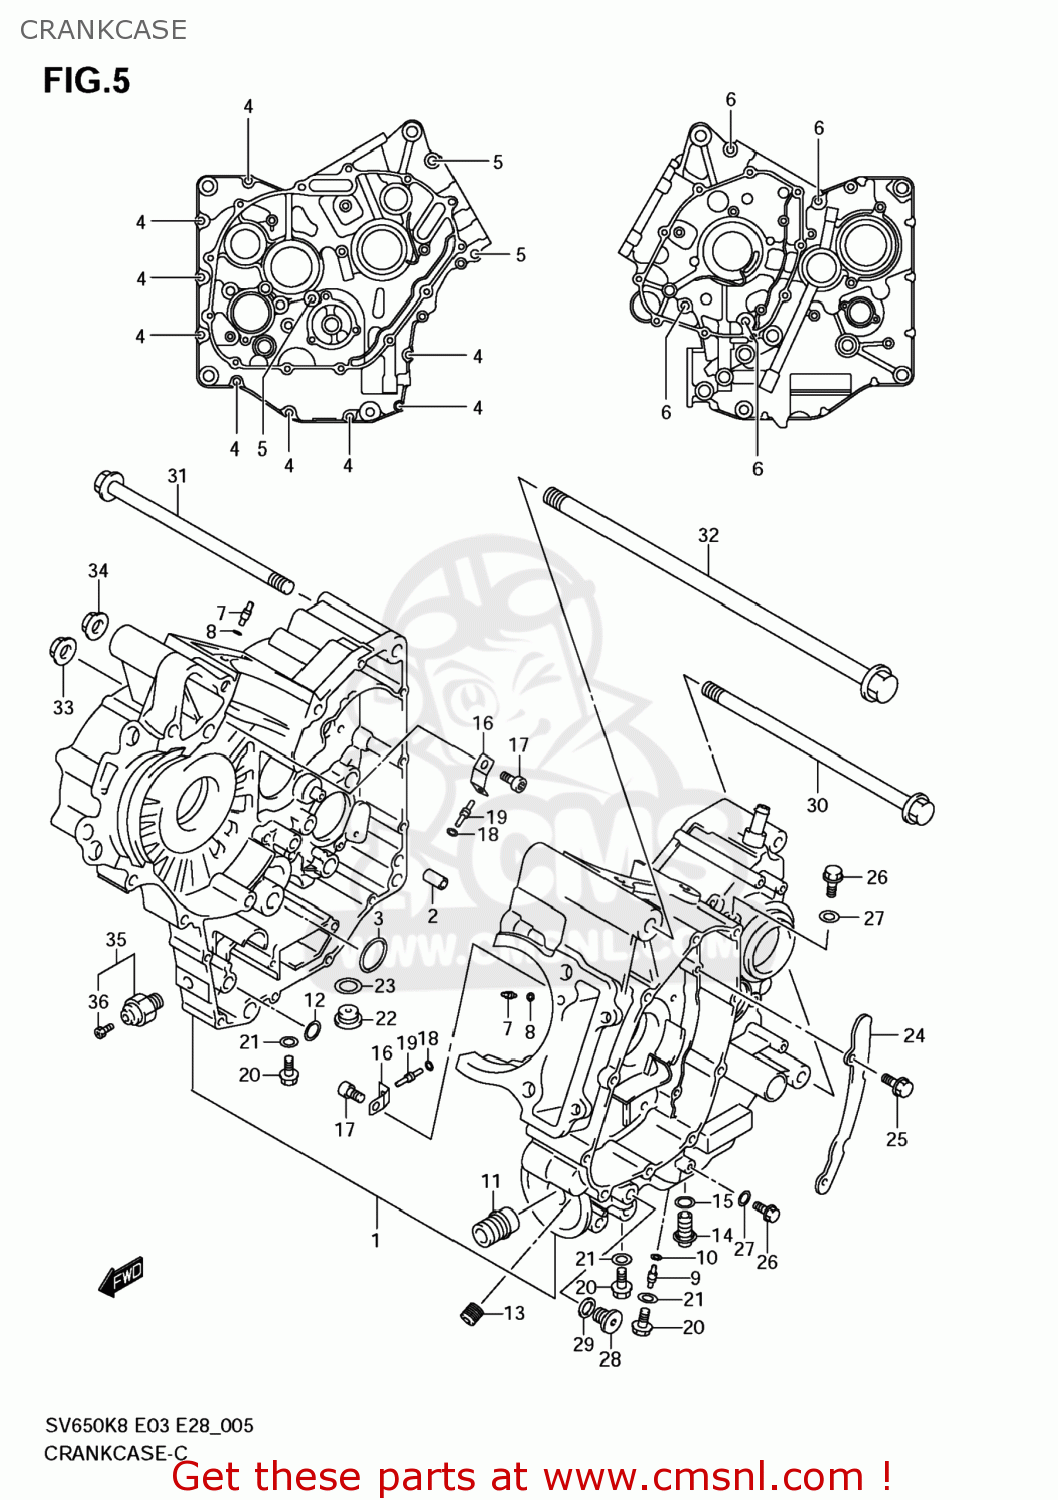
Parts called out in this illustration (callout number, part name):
1	CRANKCASE SET
2	PIN(8.4X11X20)
3	O RING(D:2.4,ID:15.8)
4	BOLT
5	BOLT
6	BOLT
7	JET,AIR(14)
8	O RING(D:1.2,ID:4)
9	JET,AIR(14)
10	O RING(D:1.2,ID:4)
11	UNION,OIL STAND
12	O RING(D:1.9,ID:12.6)
13	JET,OIL GALLERY(3.6)
14	PLUG(12X20)
15	GASKET(12.1X16.2X3.7) (NAS)
16	PLATE,PISTON COOLING JET
17	BOLT(6X12)
18	O RING(D:1.2,ID:4)
19	JET(13)
20	BOLT
21	GASKET(8.2X14X1) (NAS)
22	PLUG,16X8
23	GASKET(16X22X2) (NAS)
24	PLATE,OIL SEPARATOR
25	BOLT
26	BOLT
27	GASKET(5.8X13X1.2) (NAS)
28	PLUG(12X10)
29	GASKET(12X17X1) (NAS)
30	BOLT(10X255)
31	BOLT(10X225)
32	BOLT(12X310)
33	NUT
34	NUT
35	SWITCH ASSY,OIL PRESSURE
36	BOLT,OIL PRESSURE SWITCH
